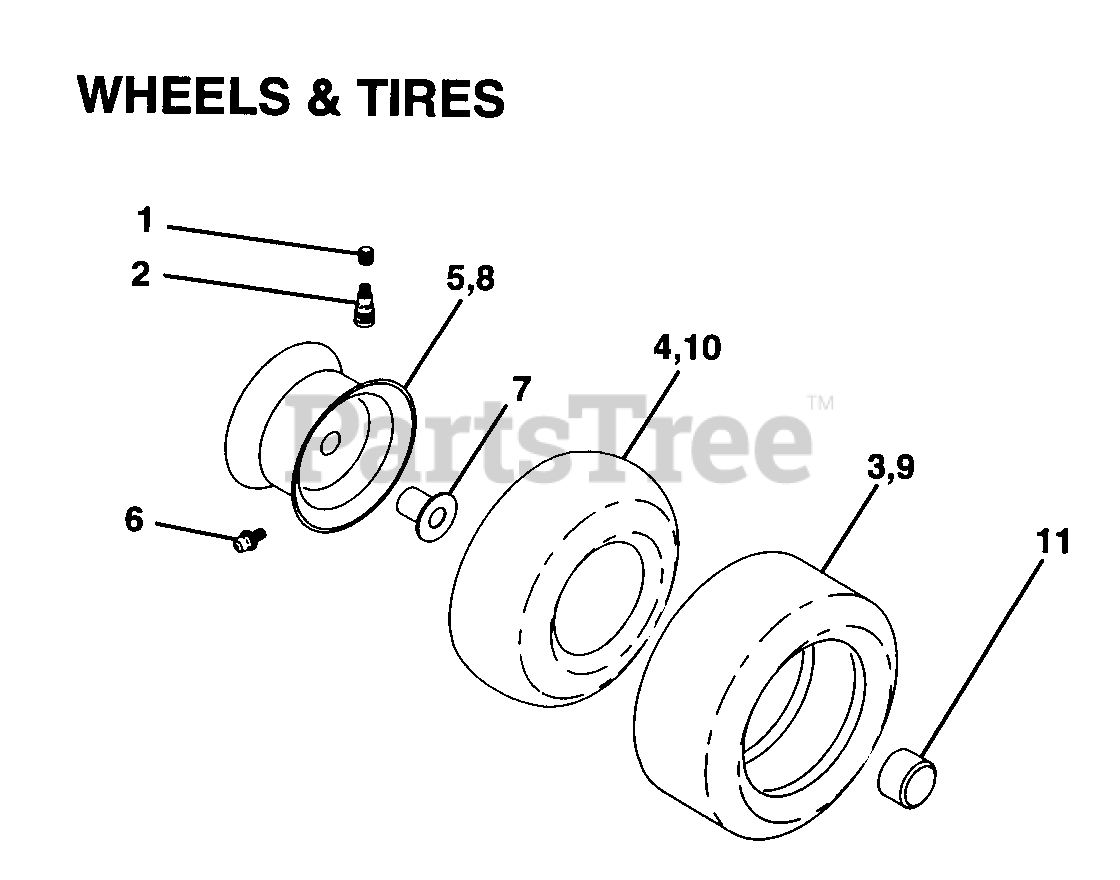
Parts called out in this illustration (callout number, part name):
1	Cap Valve Tire
2	Stem Valve
3	Tire F Ts 15 X 6 0 - 6 Service
4	Tube Front (Service Item Only)
5	Rim Asm 6"front Silver Service
6	Fitting Grease (Front Wheel Only)
7	Bearing Flange (Front Wheel Only)
8	Rim Asm 8" rear Silver Service
9	Tire R Ts 20x10-8 C Service
10	Tube Rear (Service Item Only)
11	Cap Axle Blk 1 50 X 1 00
